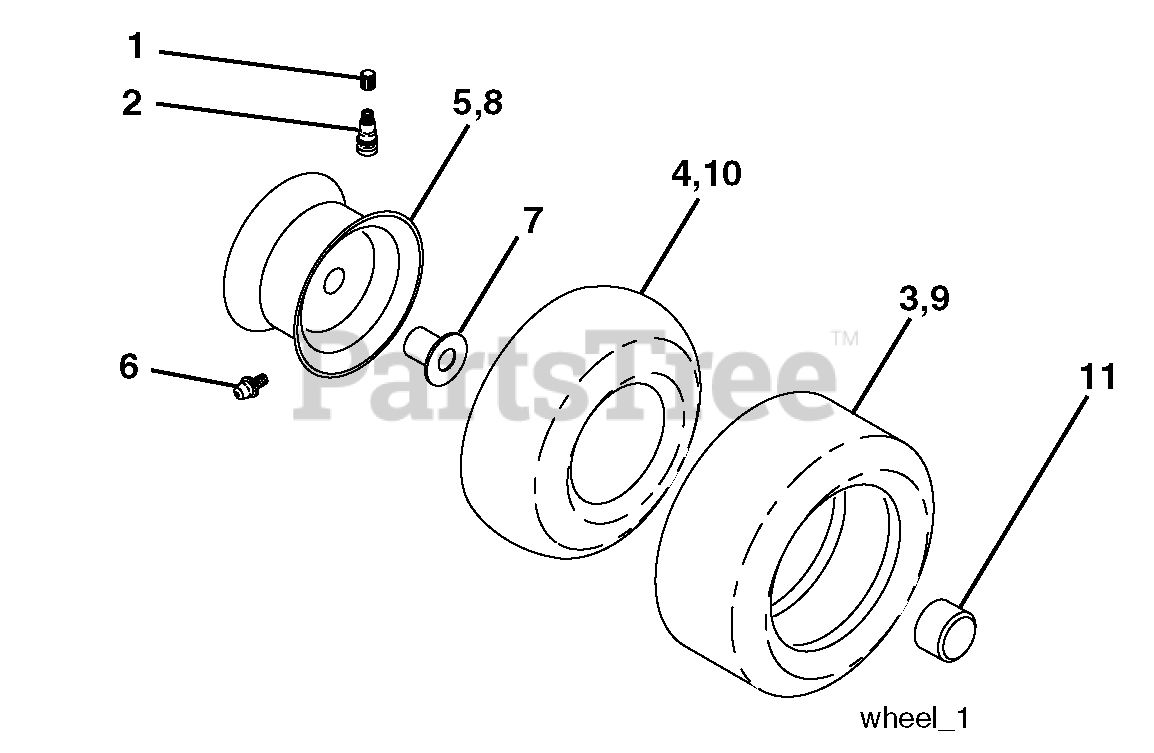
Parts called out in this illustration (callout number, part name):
1	Cap, Tire valve
2	Stem, Valve
4	Tube, Front
5	Rim assembly, 6"front
6	Fitting, Grease
7	Bearing, Flange
8	Rim assembly, 8" rear
9	Tire, Rear
10	Tube, Rear
11	Cap, Hub Axle
11	Sealant, Tire (10 oz. Tube)
